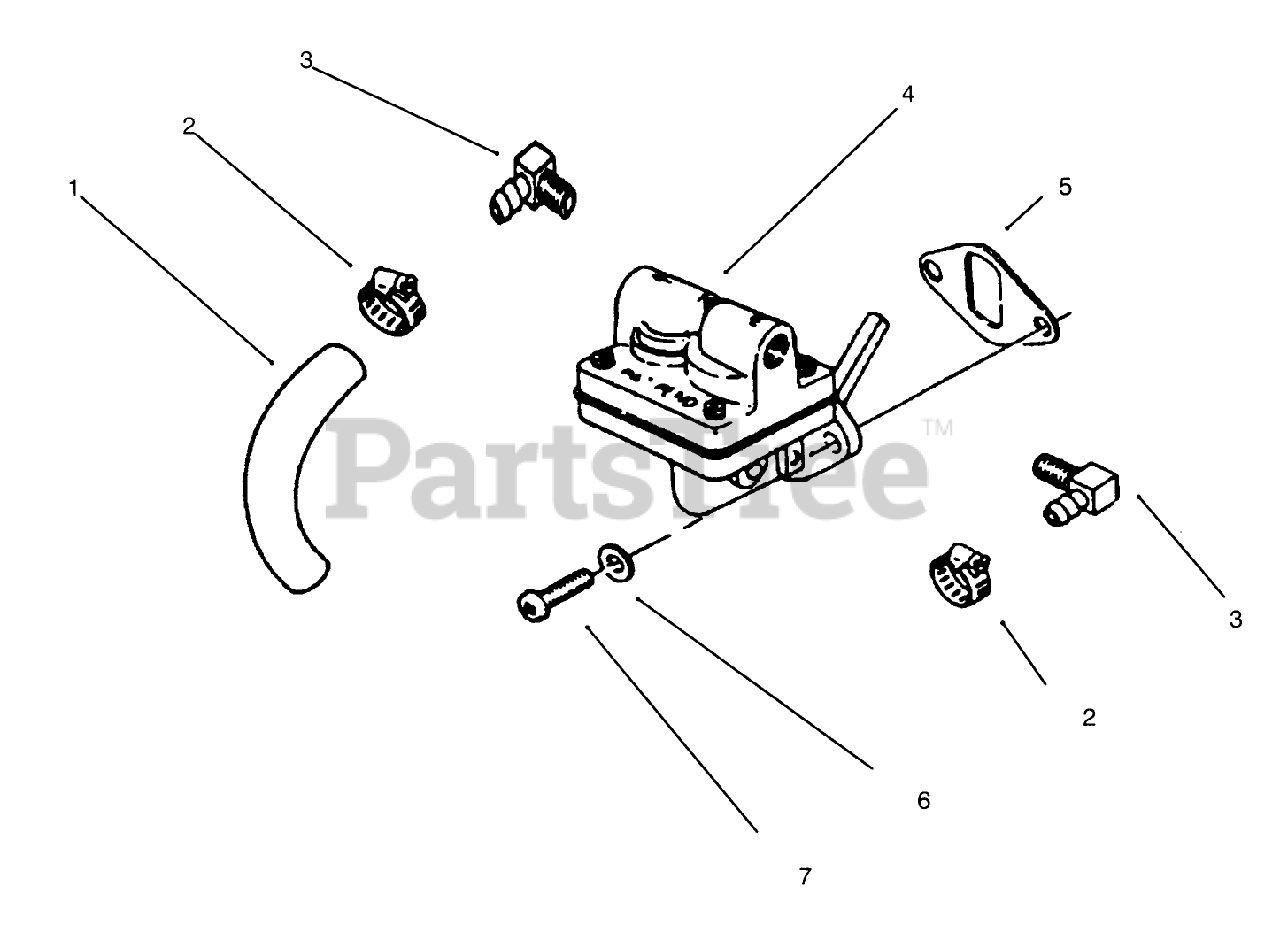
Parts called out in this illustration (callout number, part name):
1	KOHLER 25-353-01
2	KOHLER X-426-9
3	KOHLER 25-155-02
4	KOHLER 47-559-08
5	KOHLER 25-041-05
6	KOHLER X-25-63
7	KOHLER X-174-2
